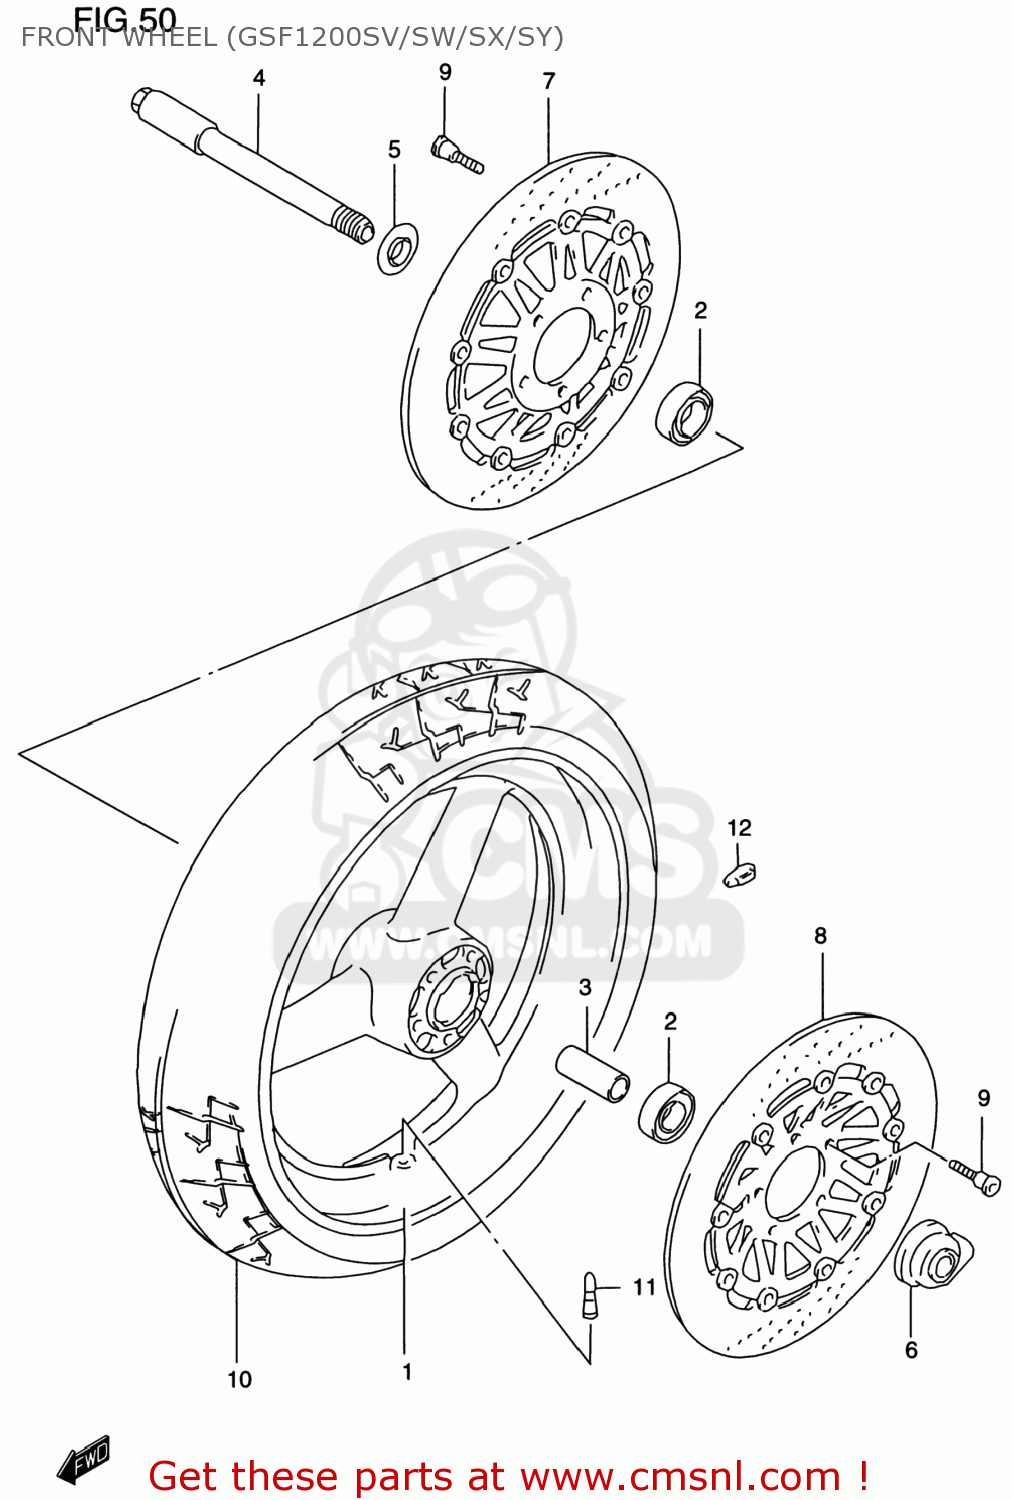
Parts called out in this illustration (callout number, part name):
1	WHEEL,FRONT (MT3.50X17)
2	BEARING
3	SPACER(20.8X27.2X74)
4	AXLE,FR
5	SPACER,FR HUB BEARING,R
6	BOX ASSY,SPEEDOMETER GEAR
7	DISC,FR BRAKE,R
8	DISC,FR BRAKE,L
9	BOLT 8X33
10	TIRE,FRONT 120/70 ZR17
11	VALVE ASSY,WHEEL RIM(TR412)
12	BALANCER,WHEEL (10G)
